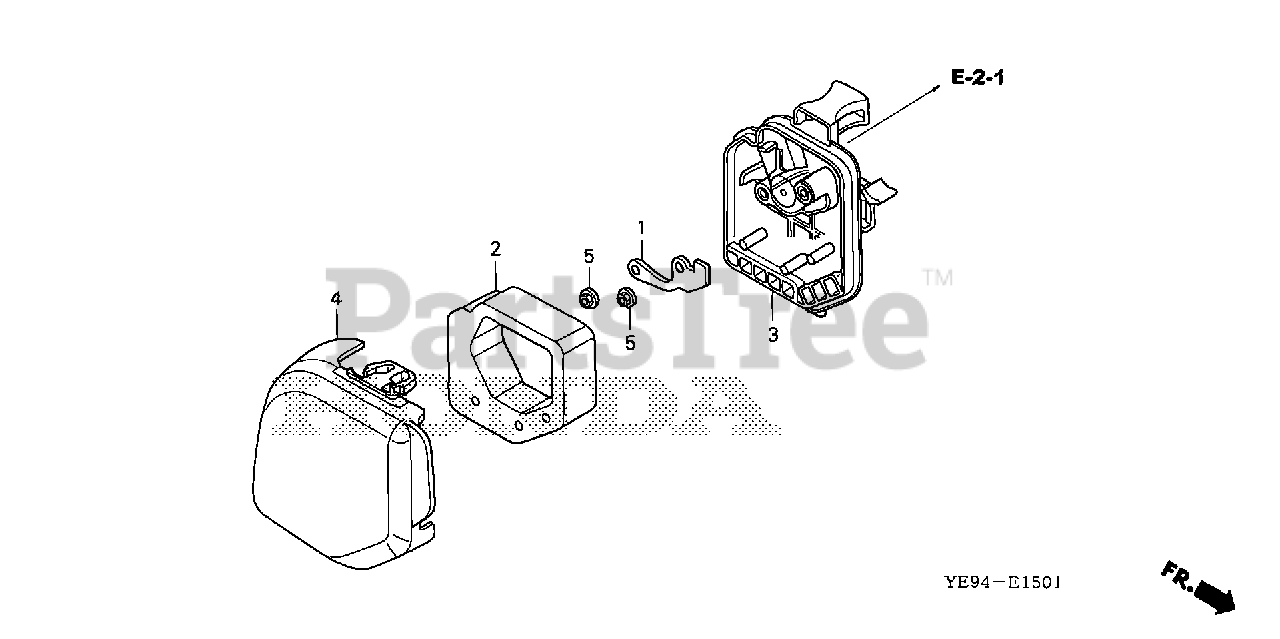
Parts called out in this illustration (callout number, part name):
1	PLATE, OIL TRAP
2	ELEMENT, AIR CLEANER
3	HOUSING, AIR CLEANER
4	COVER, AIR CLEANER
5	NUT, FLANGE (5MM)
